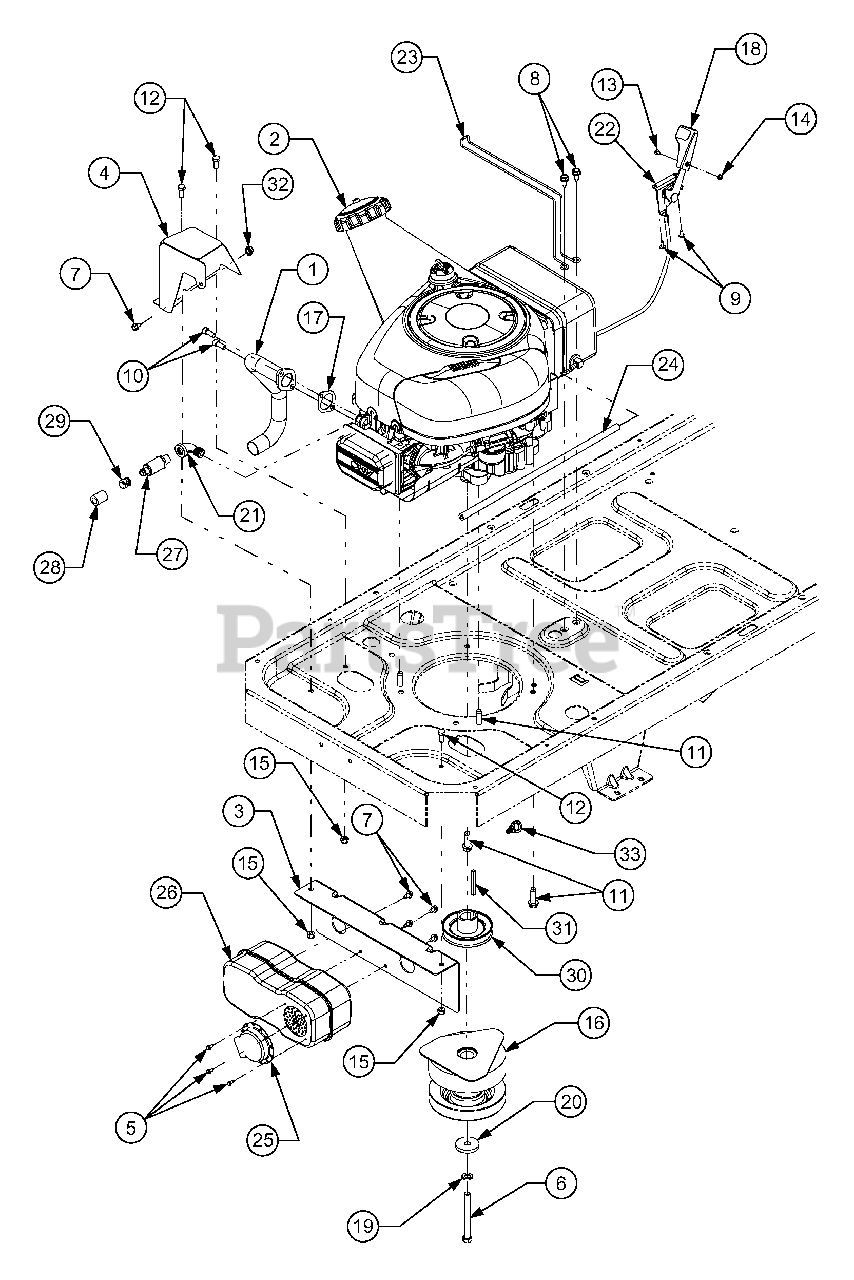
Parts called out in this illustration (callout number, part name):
1	Tube, Exhaust
2	Tank, Fuel, 3.0 Gal.
3	Bracket, Muffler Mounting
4	Shield, Muffler Tube Heat
5	Screw, Hex Wash. Hd. Tapp #8-18 x .5
6	Screw, Hex Cap, 7/16-20 x 4.0 GR5
7	Screw, Hex Wash. Hd. Tapp 1/4-20 x .5
8	Screw, Hex Wash. Hd. Tapp 5/16-12 x .75
9	Screw, Hex Wash. Hd. Tapp #12-16 x .5
10	Screw, Socket Hd. 5/16-18 x .75
11	Screw, Hex Wash. Hd. Tapp 3/8-16 x 1.25
12	Screw, Hex Cap, 5/16-18 x .75 GR5
13	Screw, Truss Hd. Mach. #8-32 x .375
14	Nut, Hex, #8-32
15	Nut, Hex Insert Lock, 5/16-18 GR5
16	Clutch Assembly, Electric PTO
17	Gasket, Exhaust (272293)
18	Knob, Throttle Control
19	Washer, Lock, 7/16
20	Washer, Flat, .438 x 1.75 x .25
21	Fitting, Elbow
22	Cable, Throttle, 39.0 Lg
23	Wire, Tank Mounting
24	Hose, Fuel Line
25	Deflector, Muffler
26	Muffler
27	Valve, Oil Drain
28	Hose, Oil Drain Extension
29	Cap, Oil Drain Valve
30	Pulley, Drive, 3.25 Dia.
31	Key, Square, 1/4 x 2.25
32	Nut, Hex Sems, 1/4-20
33	Clip, Cable Retainer
